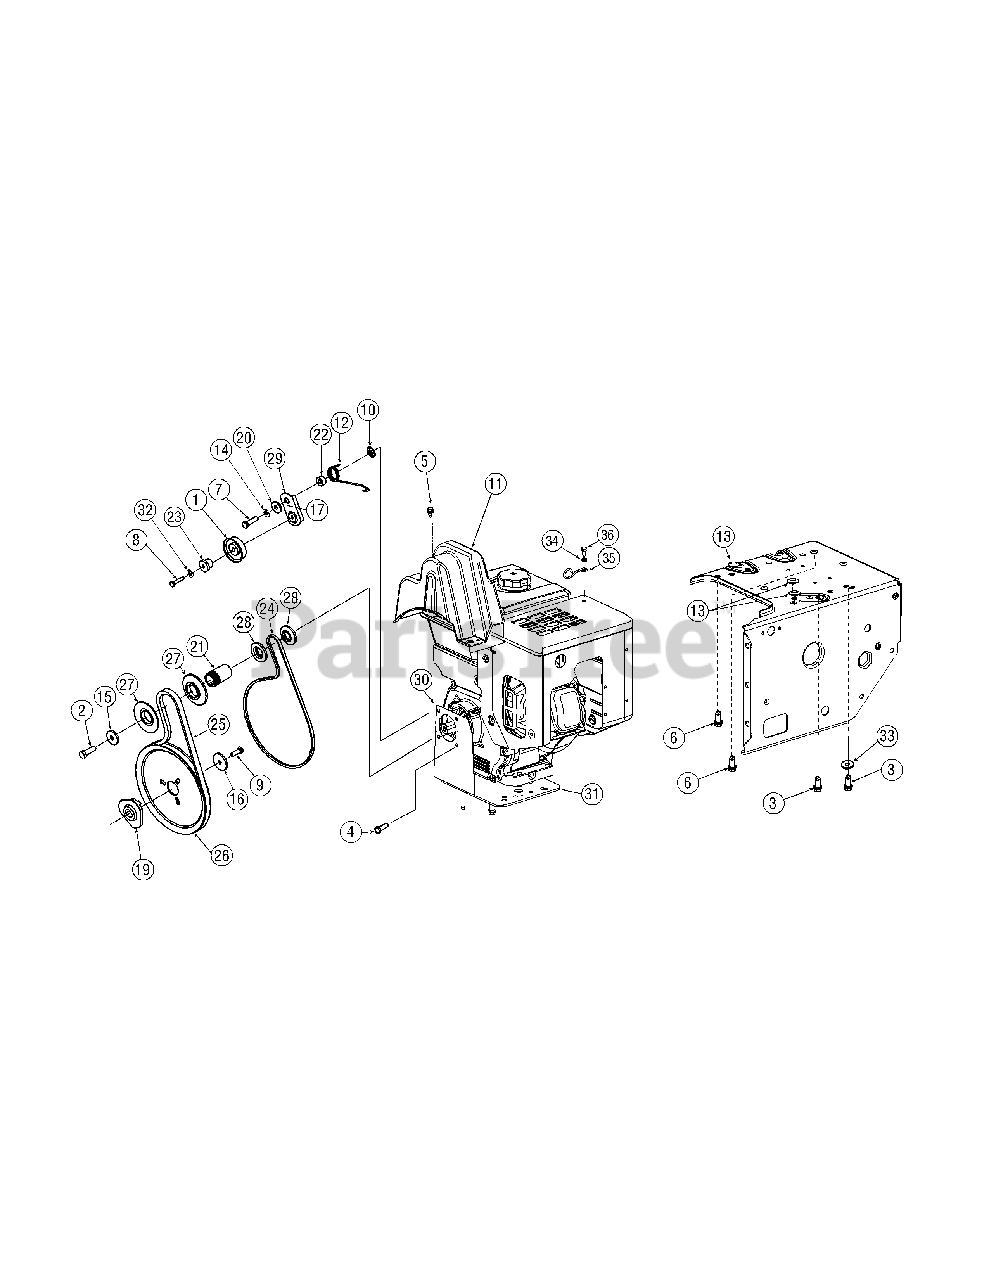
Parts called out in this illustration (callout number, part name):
1	Idler Pulley Assembly 1.917 OD
2	Hex Screw 3/8-24 x 1.25
3	Hex Washer Screw 3/8-16 x 1.25
4	Shoulder Screw .50 x .145: 5/16-24
5	Hex Wash HD Tapp Screw 1/4-20 x .375
6	Hex Wash HD Tap Screw 3/8-16 x .75
7	Hex HD. Cap Screw. 5/16-24 x 1.25 Lg.
8	Hex Bolt 1/4-20 x 1.25
9	Hex Bolt 5/16-24 x 0.875
10	Push Nut
11	Belt Cover
12	Torsion Spring .850 ID x .354" Lg.
14	L-Wash 5/16 ID
15	Flat Washer .40 ID x 1.25 OD x .160
16	Flat Washer .34 x 1.50 x .150
17	Grease Arctic: EP
19	Pulley Adapter
20	Shld. Spacer .3175 x .5 x .1025
21	Spacer .875 ID x 1.185 OD
22	Spacer .340 x .750 x .360" Lg.
24	V-Belt 3/8 x 35.68" Lg.
25	Belt .5 x 37.0" Lg.
26	Auger Pulley
27	Pulley Half
28	Pulley Half 3/8 V x 1.71 OD
29	Wheel Drive Idler Bracket
30	Cover Plate
32	L-Wash 1/4 ID
33	Flat Washer .38 x 1.38 x .125
34	Flat Washer .330 ID x .630 OD x .0635
35	Cable Guide
36	Hex Hd. Cap Screw. MB-1.25:20 Gr. 8
